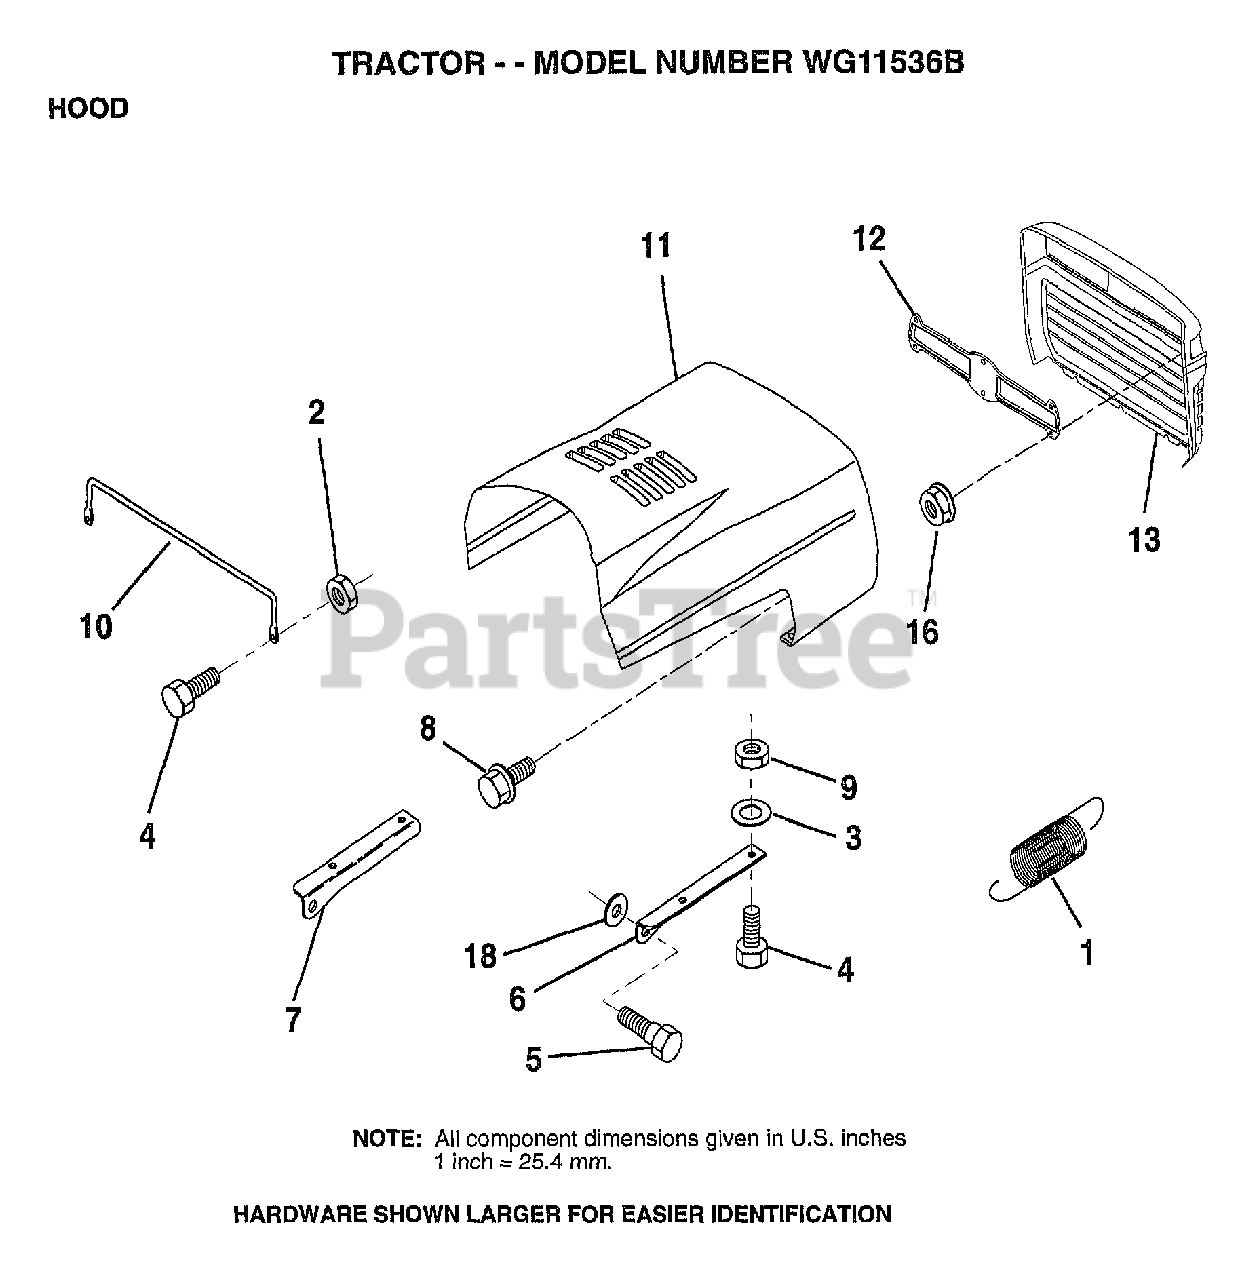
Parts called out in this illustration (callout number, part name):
1	EXT SPRING
2	NUT
3	WASHER
5	BOLT.SHLD.5/16-18
6	BRKT HOOD RH
7	BRKT HOOD LH
8	SCREW SLTD HXHD
9	NUT
10	"BRACE,HOOD"
11	HOOD.IMPREG.MS550
13	GRILL (BLACK)
16	NUT
18	WASHER
